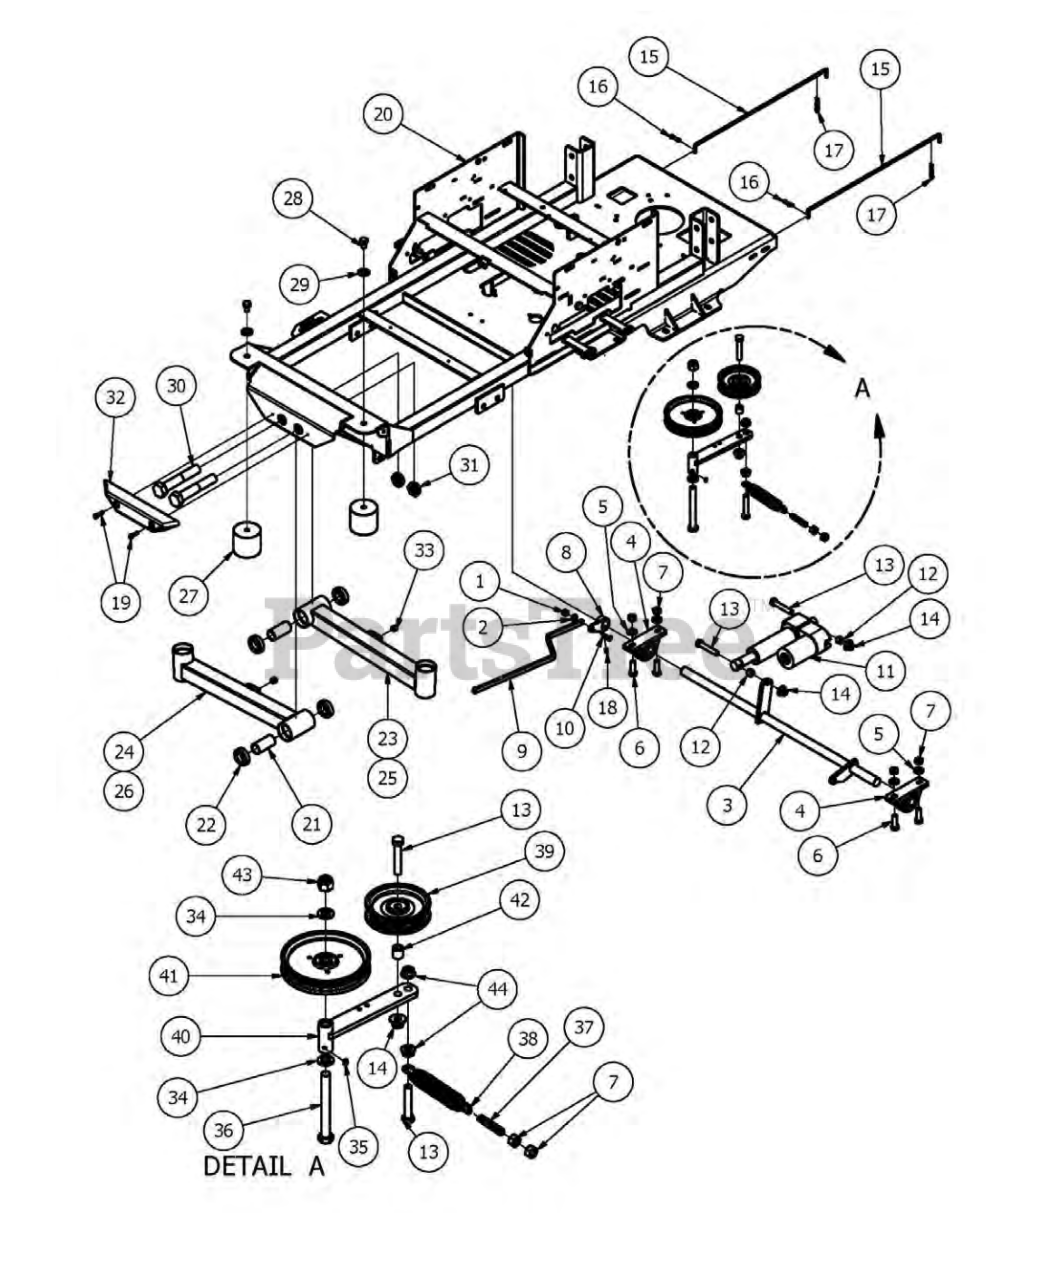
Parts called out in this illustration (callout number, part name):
1	5/16-18 Nylon Flange Nut
2	.360 ID Plastic Washer
3	Actuator Bar-ZT
4	pillow block 2bolt sealmaster
5	1/2" Lock Washer Zinc
6	1/2" x 1 1/2" Hex Bolt
7	1/2" Hex Nut
8	Height Indicator Lever
9	Height Indicator Bar
10	5/16" x 1" Bolt
12	1/2 x 1/2 Spacer
13	1/2" x 2 3/4" Hex Bolt
14	1/2-13 Nylon Flange Nut
15	ZT Neutral level rod 2011
17	Neutral Rod Clip
18	5/16 Set Screw
19	1/4 x 1 Hex Head Tek screw
20	2016 Maverick Frame
21	2016 Front Bearing Spacer
22	Caster Bearing 2016 - 1641 Bearing
23	Front Arm Assembly - Long (left)
24	Front Arm Assembly - Long (Right)
25	Front Arm Assembly - Short (left) (48" Deck Only)
26	Front Arm Assembly - Short (Right) (48" Deck Only)
27	Vibration Mount- Red Dot
28	1/2" x 3/4" Hex Bolt
29	1/2" Washer (Grade 8)
30	1-14 x 5.5 Hex Bolt Grade 8 Zinc Yellow
31	1" Fine Thread 1/2 Nylock Nut
32	Front Bumper
33	5/8 Round Insert
34	.630 ID Plastic Washer
35	1/4" Press in Grease Fitting
36	5/8" x 5 1/2 Hex Bolt
37	All Thread-Pump Idler Tensioner
38	2009 Deck/Pump Idler Spring
39	4 3/4" Idler Pulley
40	Deck Idler
41	5-3/4 Idler Pulley 5/8 Bore
42	Spacer 3/4 OD x 1/2 ID x 3/4 Length
43	5/8 Std NC Nylock Nut
44	1/2" Flange Nut
